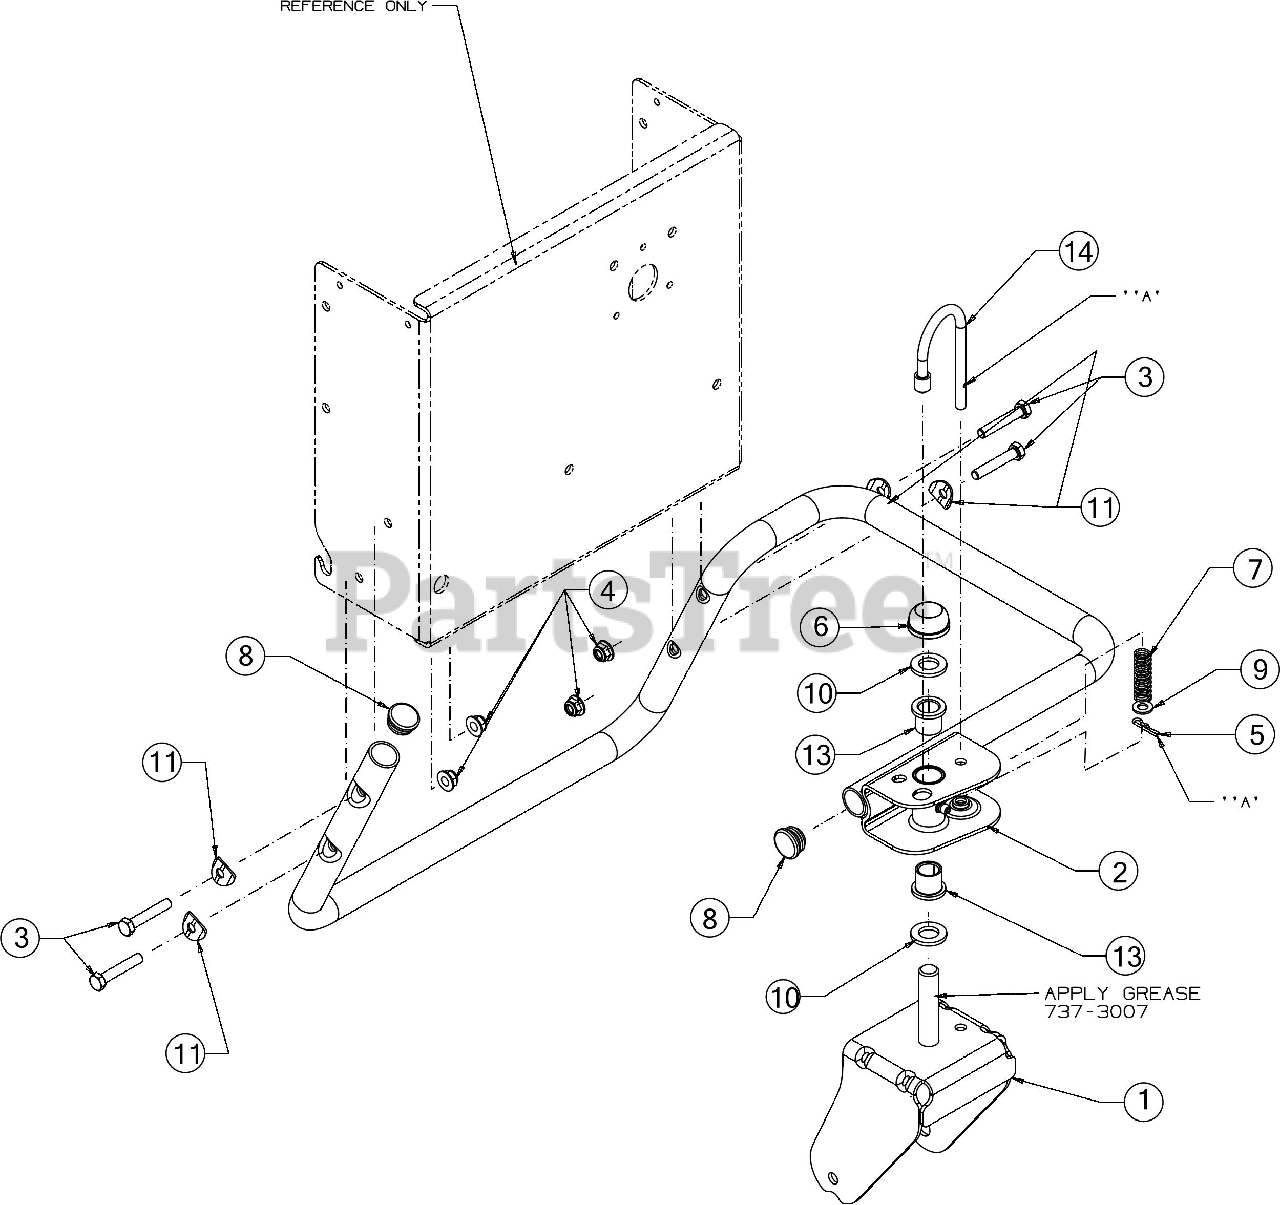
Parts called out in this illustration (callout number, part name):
1	WHEEL BRACKET ASSEMBLY
2	LOWER FRAME ASSEMBLY
2	FLAT WASHER
2	GREASE FITTING
3	SCREW 5/16-18 x 1.75 GR5
4	FLANGE LOCK NUT 5/16-18
5	COTTER PIN .072 DIA
7	COMPRESSION SPRING
9	FLAT WASHER
10	FLAT WASHER
11	SADDLE WASHER
12	GREASE-#251 EP (NOT SERVICEABLE)
13	BEARING:FLANGE .631 ID
